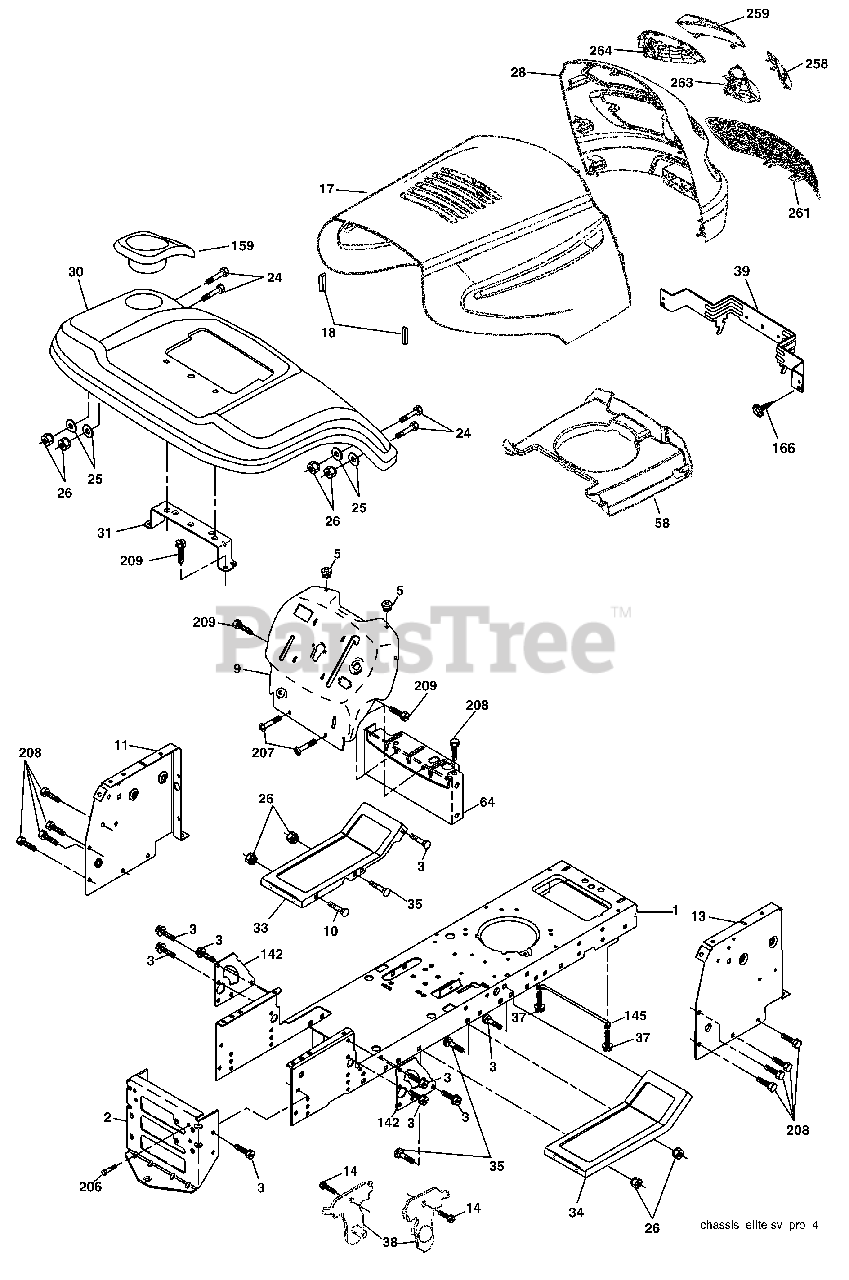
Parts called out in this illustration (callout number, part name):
1	Chassis
2	Drawbar
3	Screw 3/8-16 x 3/4
5	Bumper Hood/Dash
9	Dash
10	Bolt Rd Hd Sqnk. 3/8-16 Unc x 1
11	Panel Asm. Dash Lh
12	Clip Tinnerman Grile P/L
13	Panel Dash Rh
14	Screw Thdrol 3/8-16 x 1/2
17	Hood
18	Bumper Hood
24	Bolt Fin Hex 3/8-16 Unc x 1 Gr. 5
25	Washer 13/32 x 13/16 x 12 Ga.
26	Nut Lock Hex w/Insert 3/8-16 UNC
28	Grill/Lens Asm
30	Fender Asm
31	Bracket Fender
33	Footrest LH
34	Footrest RH
35	Bolt Rd Hd Sht. Sqnk. 3/8-16 x 3/4
37	Screw Thdrol 5/16-18 x 1/2 Tyt
38	Bracket Asm. Pivot Mower Rear
39	Bracket Pivot
58	Air Duct
64	Dash Lower
142	Plate Reinforcement
145	Rod Pivot Chassis/Hood
159	Cupholder
166	Screw #13-16 x 3/4
206	Bolt shoulder 5/16-18
207	Screw Thdrol 5/16-18 x 1/2
208	Screw Thdrol 3/8-16 x 1/2
209	Screw 3/8-16 x 3/4
258	Lens Grille RH
259	Lens Grille LH
263	Bezel Grille LH
264	Bezel Grille RH
